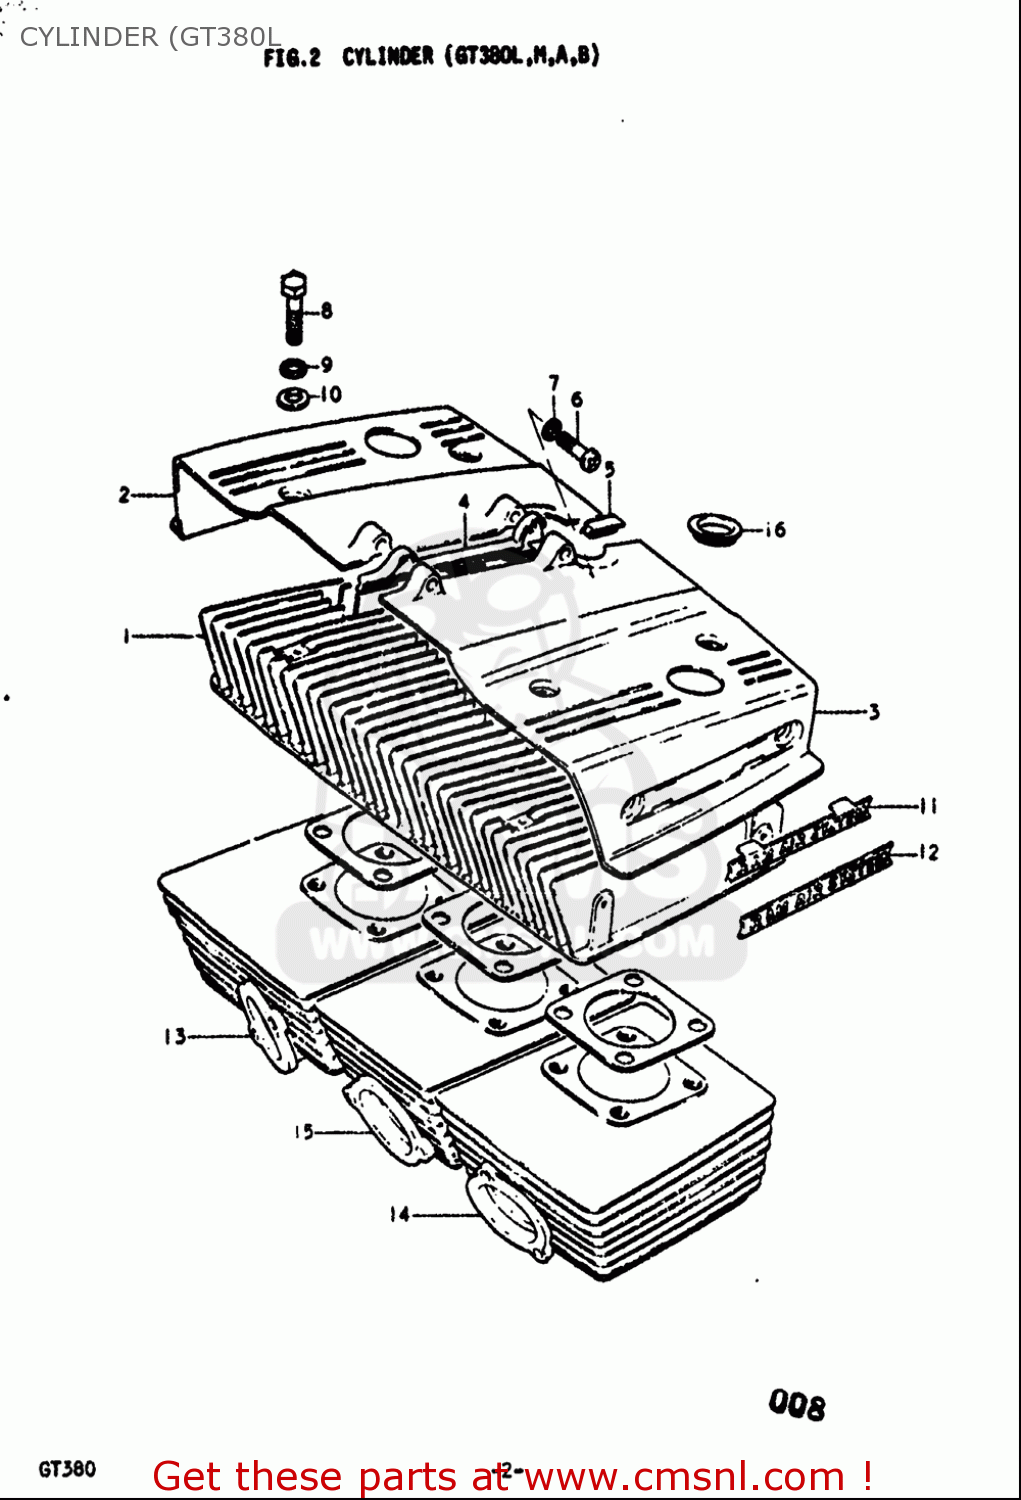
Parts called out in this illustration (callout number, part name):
6	SCREW
7	WASHER,LOCK
8	BOLT
9	WASHER,LOCK
10	WASHER
11	EMBLEM,CYLINDER HEAD COVER
12	EMBLEM,CYLINDER HEAD COVER
16	RING, SPARK PLUG
